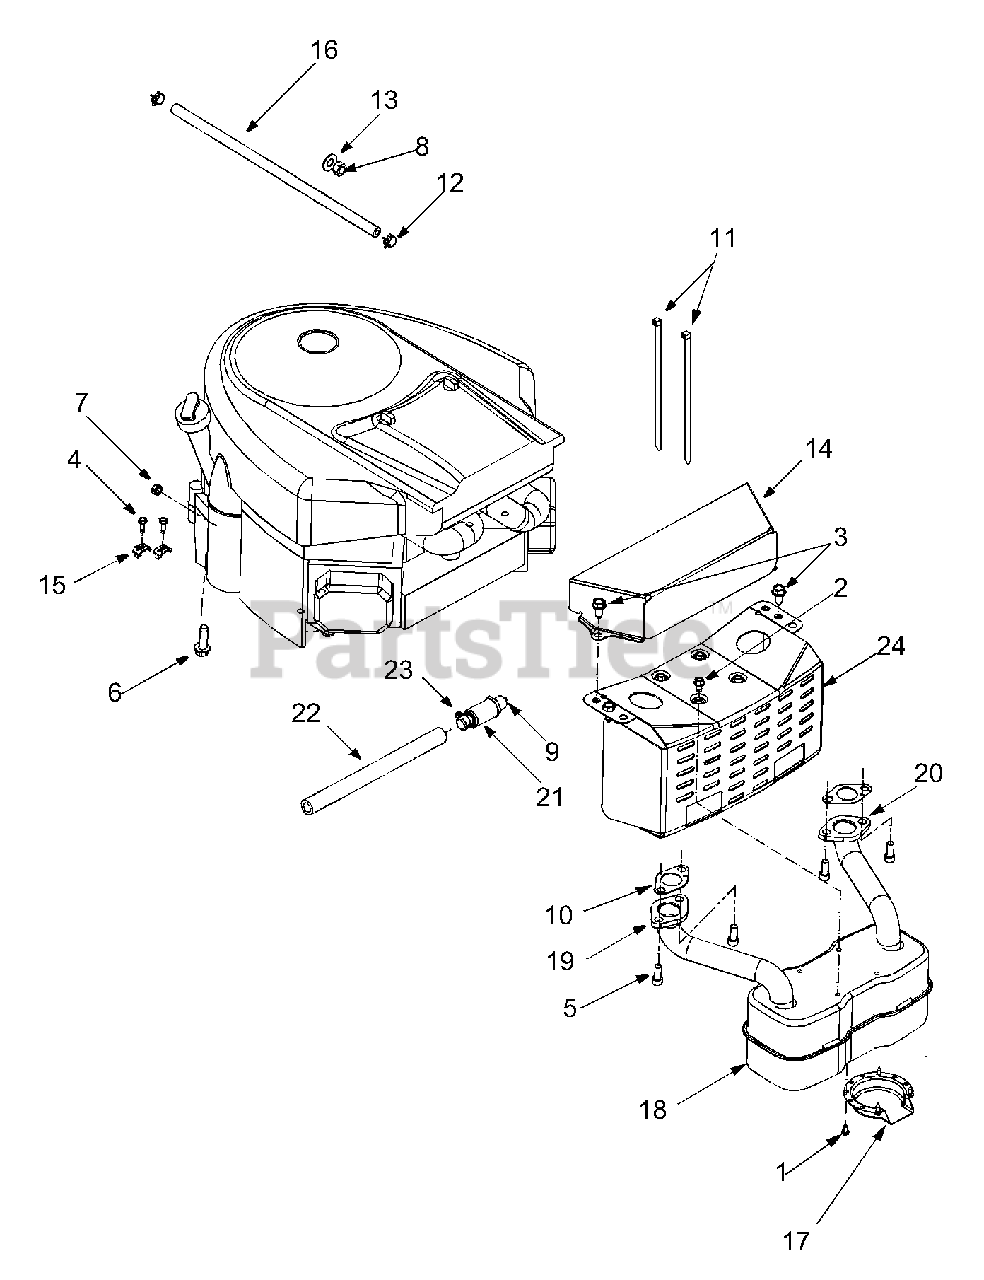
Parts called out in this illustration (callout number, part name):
1	Screw #8-18 x 0.5
2	Self-tapping Screw 1/4-20 x 0.5
3	Screw 5/16-12 x 0.75
4	Screw #10-32 x 0.625
5	Socket Hd. Screw 5/16-18 x 0.75
6	Self-tapping Screw 3/8-16 x 1.25
7	Sems Nut
8	Hex Nut 3/8-16
9	Pipe Sealant
10	Exhaust Gasket
11	Cable Tie
12	Hose Clamp
13	Flat Washer
14	Heat Shield
15	Clamp: Casing
16	Fuel Line Hose
17	Muffler Deflector
18	Dual Inlet Muffler
19	Exhaust Pipe RH
20	Exhaust Pipe LH
21	Oil Drain
22	Hose Extension: Oil Drain
23	Oil Drain Cap
